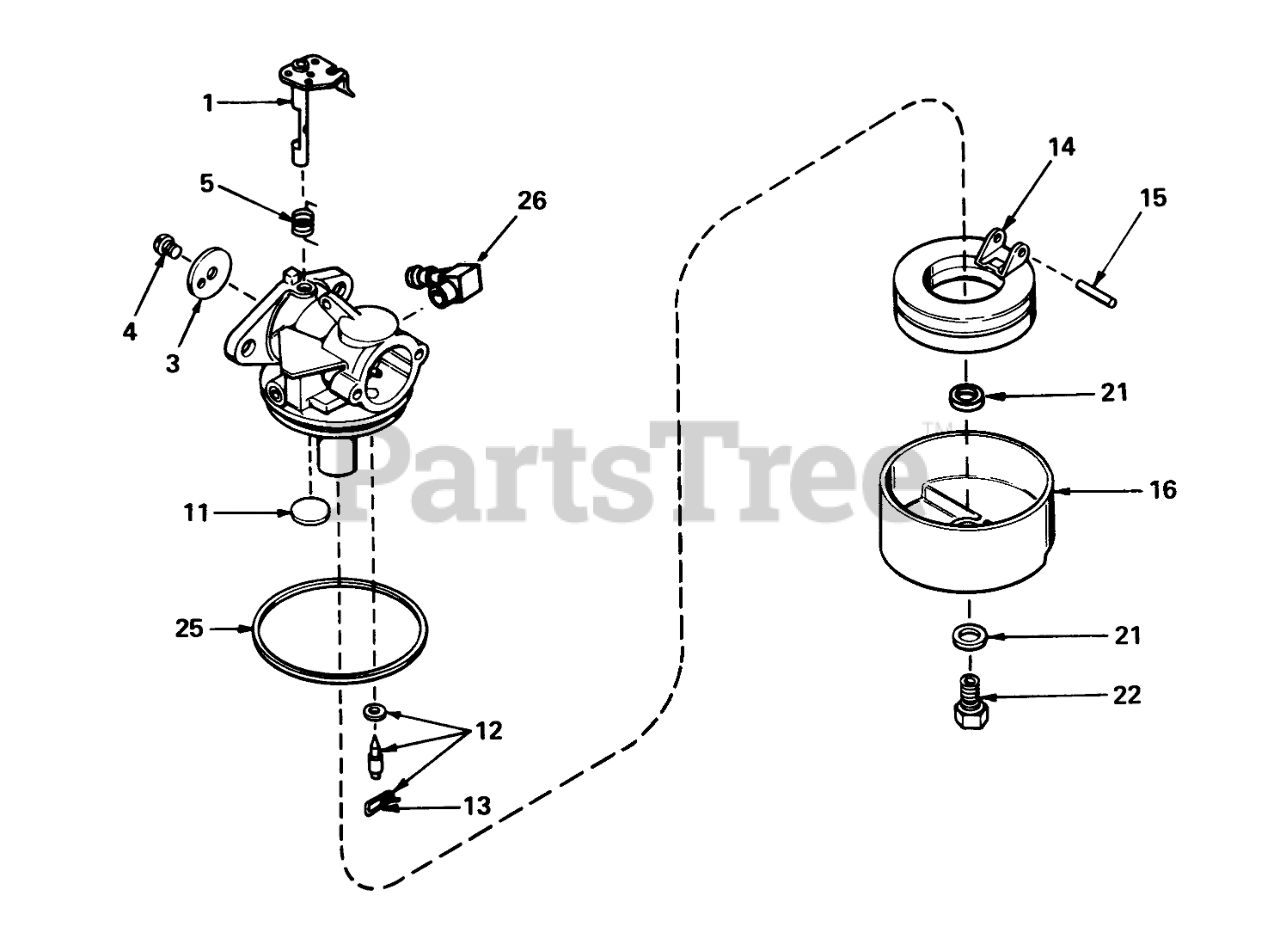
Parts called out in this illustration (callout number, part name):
1	Throttle Shaft and Lever ASM
3	Throttle-Shutter
4	Screw-Shutter
5	Spring, Return
11	Plug-Welch, Atmospheric Vent
12	Inlet Needle, Seat & Clip Assembly (Incl. No. 13)
13	Clip-Spring
14	Float,Carburetor
15	Shaft-Float
16	Bowl Float
21	Gasket-Bowl
22	Nut, Float Bowl
25	O Ring-Bowl, Float
26	Fitting-Fuel
